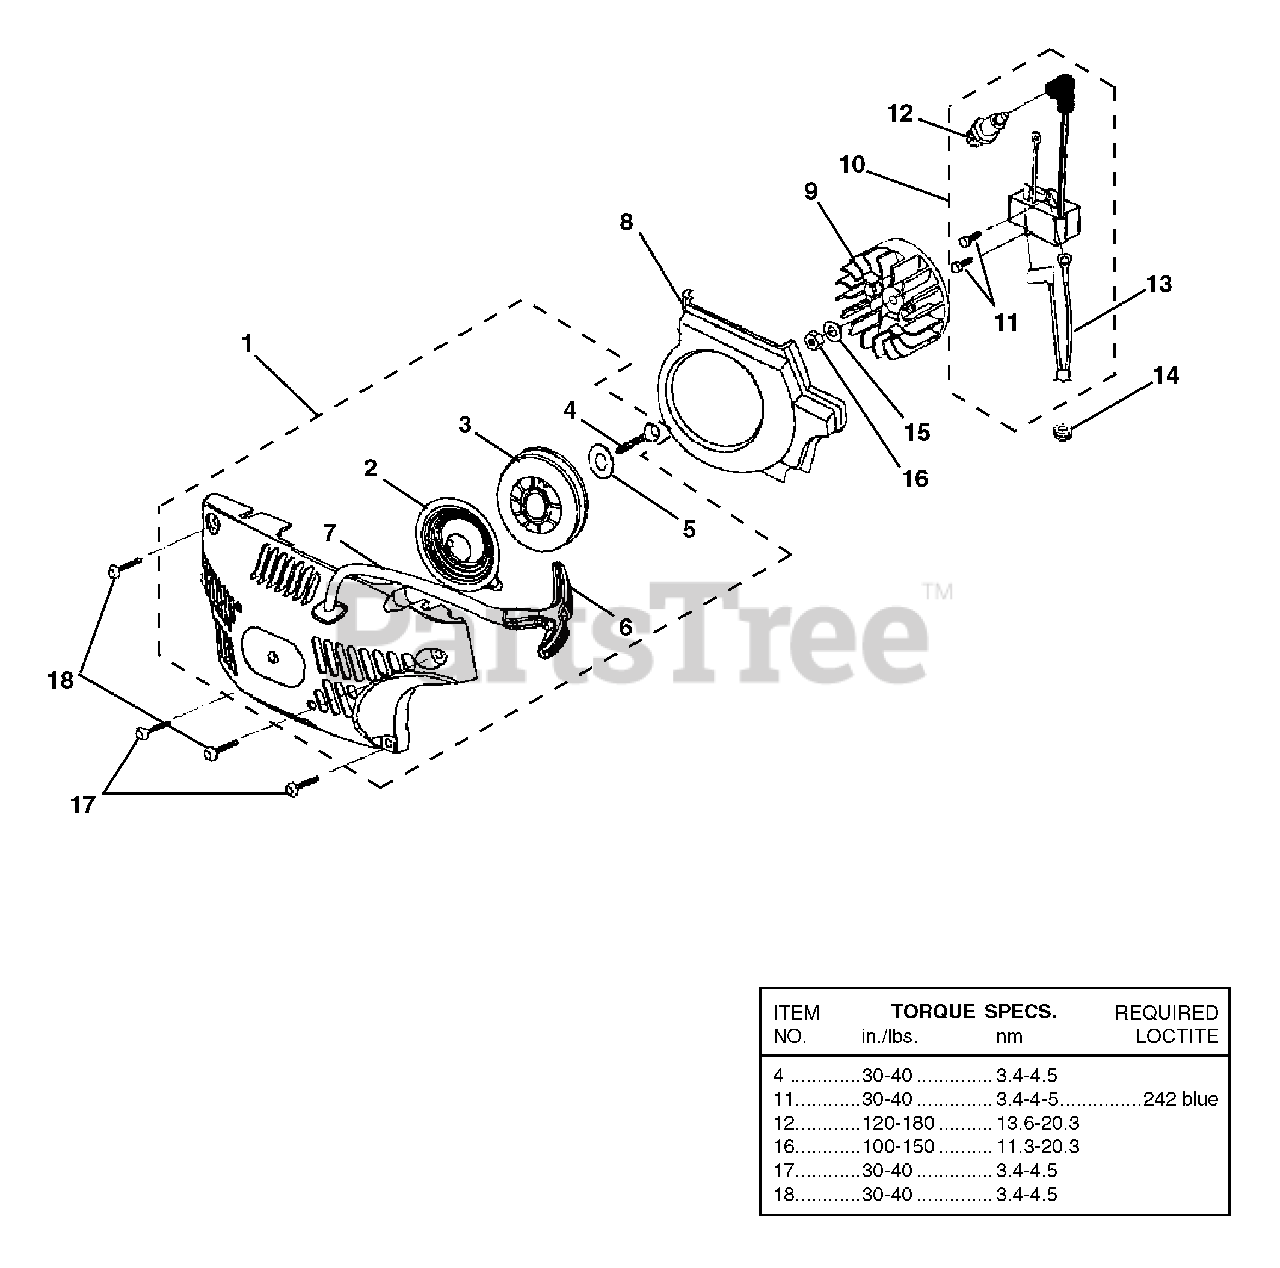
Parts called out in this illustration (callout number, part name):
1	STARTER HOUSING ASSEMBLY
2	SPRING & CONTAINER
3	STARTER PULLEY
4	SCREW, THREAD FORM, PLASTITE (10-14 X 5/8 in.)
5	WASHER RETAINING
6	GRIP STARTER
7	STARTER ROPE (46 in.)
8	BAFFLE, FAN HOUSING
9	ROTOR & STARTER PAWL
10	IGNITION KIT (33 cc)
11	SCREW, THREAD FORM (8-32 x 5/8 in.)
12	SPARK PLUG
13	IGNITION SWITCH HARNESS
14	GROMMET, WIRE HARNESS (SPLIT) 1
15	WASHER, FLAT
16	JAM NUT
17	SCREW, TRUSS HD. PLASTITE (10-14 x 7/8 in.)
18	SCREW, TRUSS HD. PLASTITE (10-14 x 5/8 in.)
